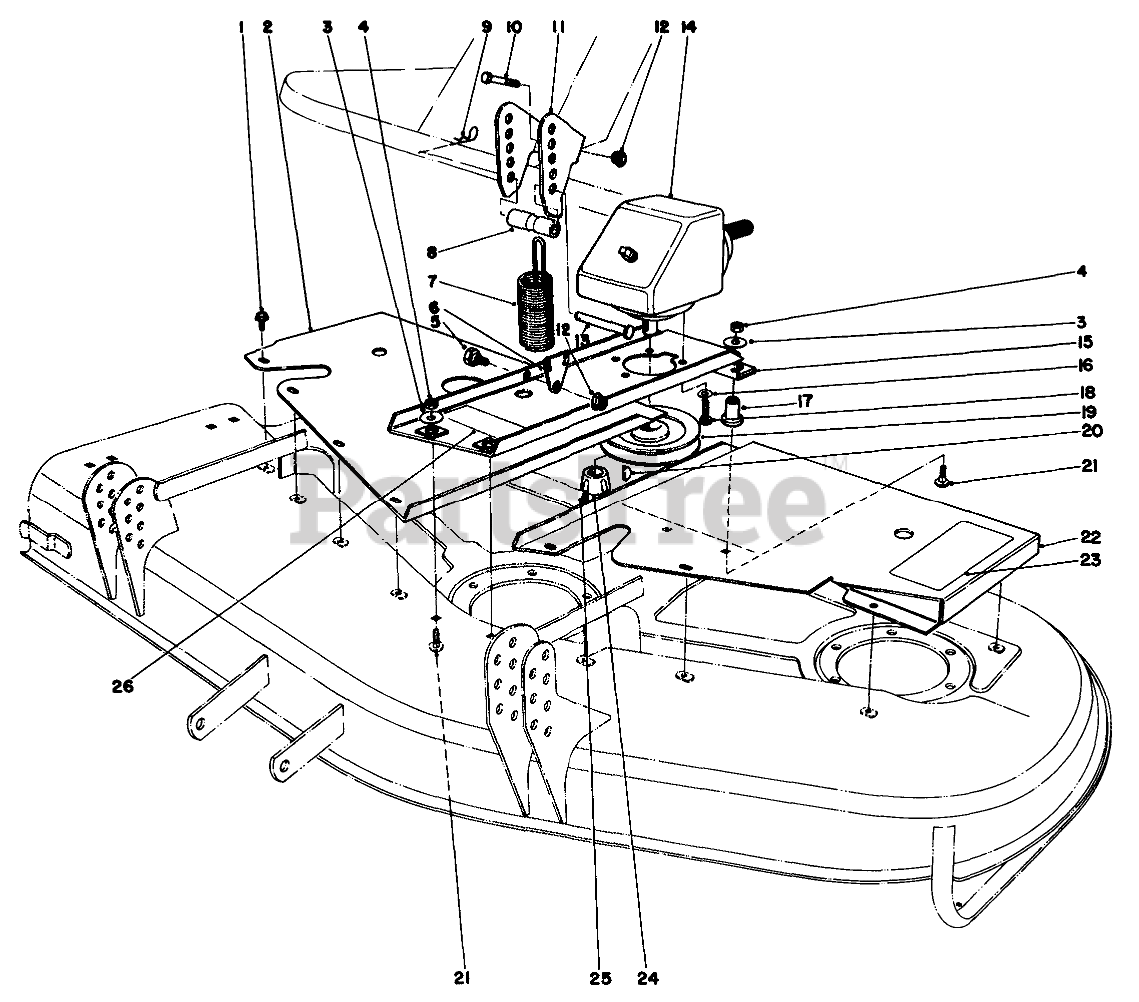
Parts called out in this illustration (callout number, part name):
1	SCREW-HHFTF
2	RH COVER WA R
3	WASHER
4	NUT-LOCK, SIDE
5	BOLT-SHOULDER
6	SPRING END R
7	Spring-Extension
8	SPACER
9	PIN-HAIR
10	SCREW-HH
11	SPRING BRACKET R
12	NUT-HHF, WHIZ
13	PIN-CLEVIS
14	Gear Box
15	GEARBOX BASE WA R
16	WASHER-LOCK
17	MOUNT
18	SCREW-HSH
19	PULLEY
20	KEY-WOODRUFF
21	SCREW-CARR
22	LH COVER WA R
23	DECAL
24	BUSHING-LOCK, TAPER
25	SCREW-SET, HSH
26	Decal-Caution
